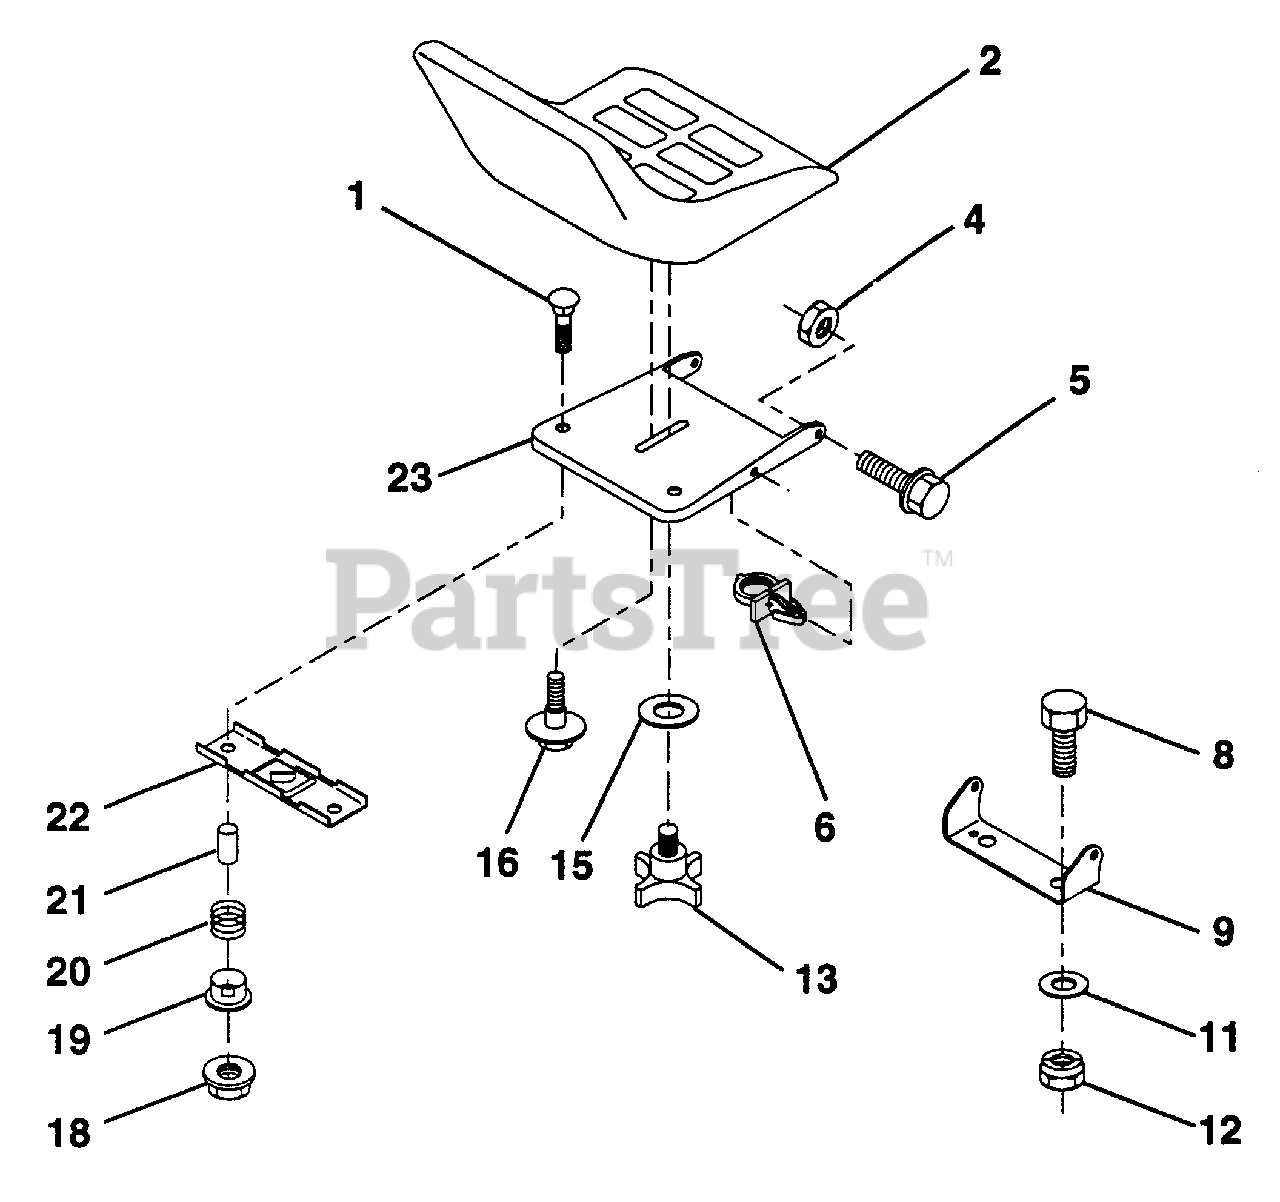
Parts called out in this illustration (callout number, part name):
1	Bolt, Carriage 1/4-20 x 1-3/8
2	Seat
4	Nut, Hex, Crownlock 5/16-18
5	Bolt, Shoulder 5/16-18 UNC
6	Clip, Insulated
8	Bolt, Hex, Fin. 3/8-16 UNC x 3/4
9	Bracket, Pivot, Seat
11	Washer 12/32 x 2 x 10 Gauge
12	Nut, Hex, Crownlock 3/8-16 UNC
13	Knob, Seat
15	Washer 17/32 x 1-3/16 x 12 Gauge
16	Bolt, Shoulder
18	Nut, Hex, Large, Flange Lock
19	Bushing, Snap
20	Spring, Compression
21	Spacer, Split, Large .28 Id. x .96
22	Bracket, Switch Mounting
23	Pan, Seat
